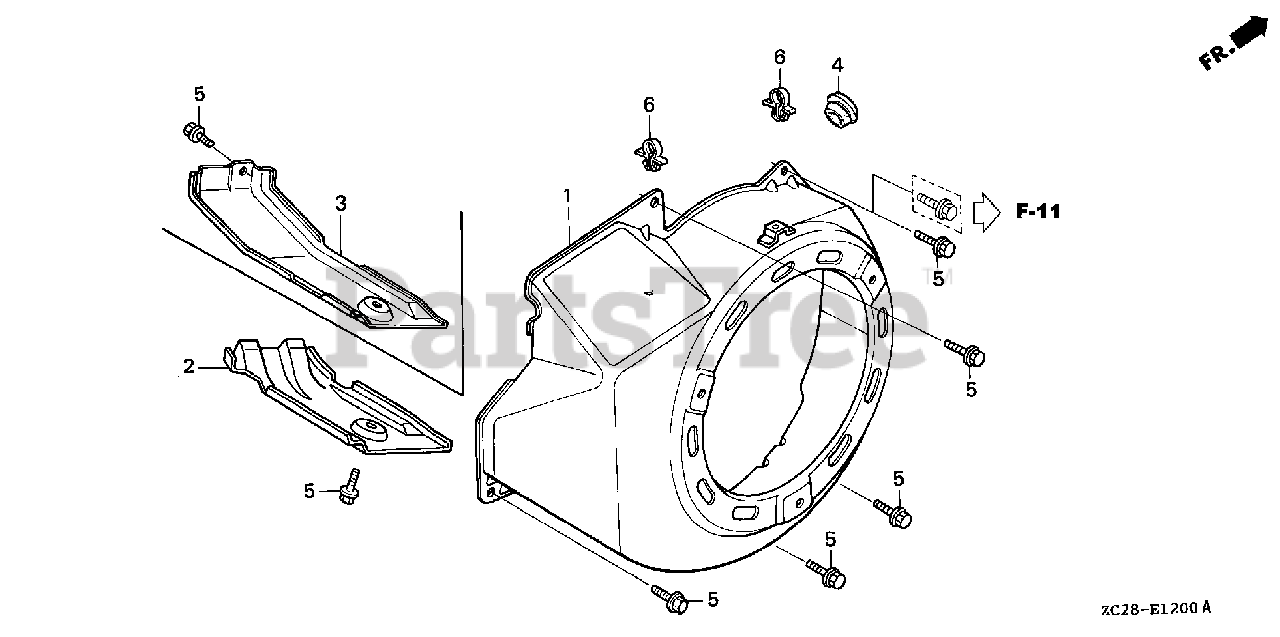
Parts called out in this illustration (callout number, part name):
1	COVER, FAN *R8* (BRIGHT RED)
4	GROMMET, DRAIN HOLE
5	BOLT, FLANGE (6X12) (CT200)
6	CLIP, WIRE HARNESS (6MM) (WHITE)
